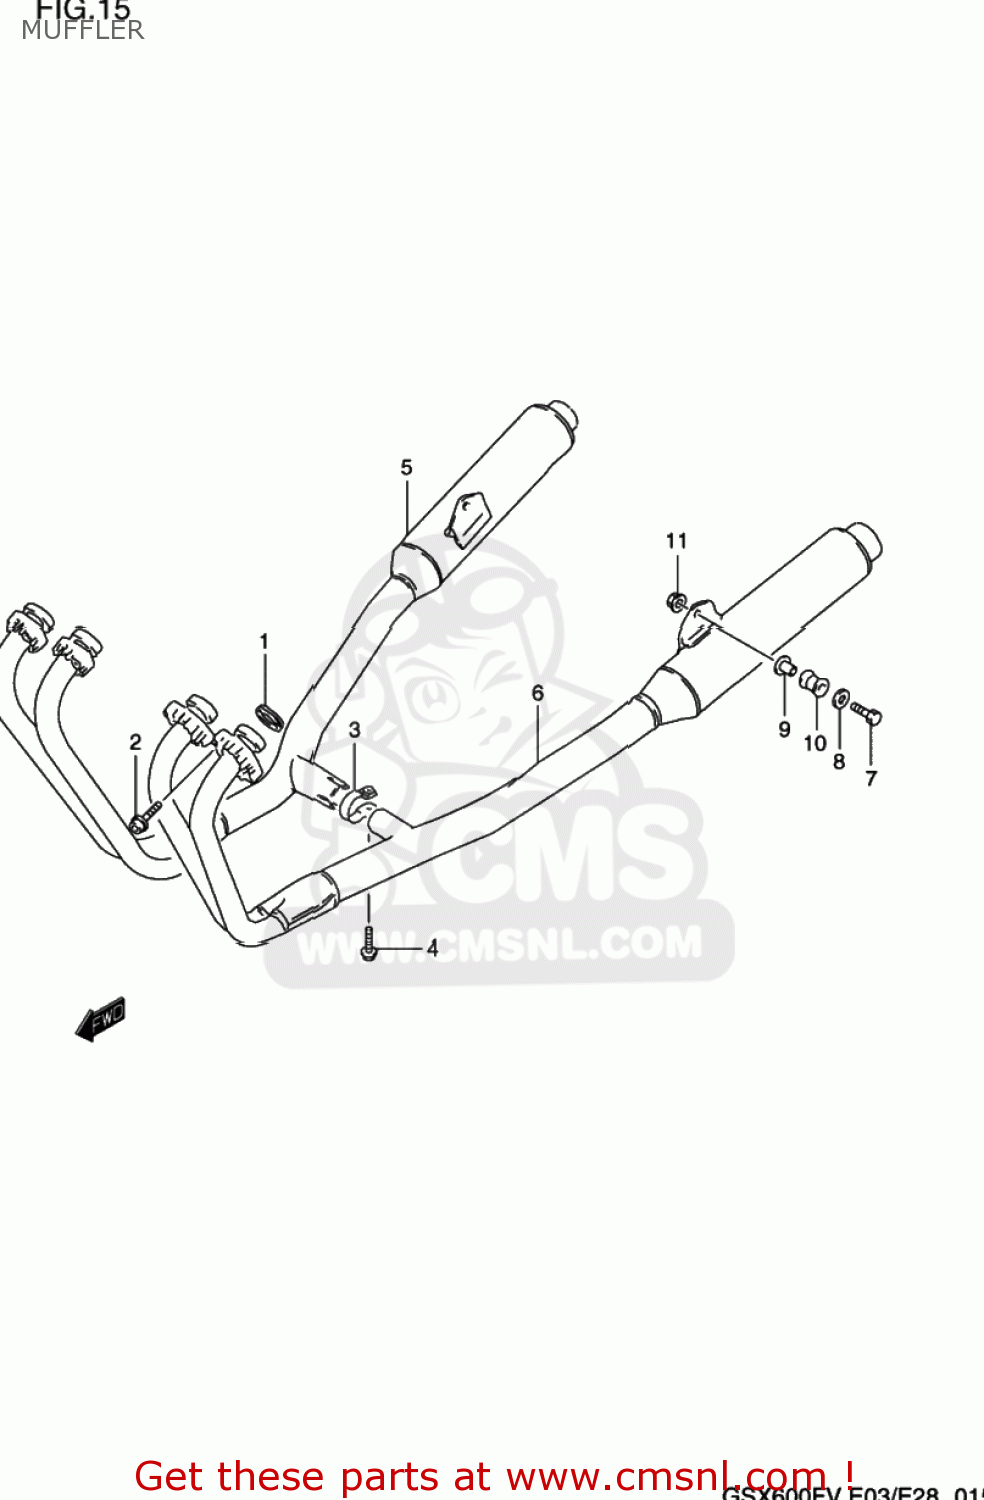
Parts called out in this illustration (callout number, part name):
1	GASKET,EXHAUST (NAS)
2	BOLT
3	CLAMP,MUFFLER CONNECTOR
4	BOLT
5	MUFFLER ASSEMBLY,RIGHT
6	MUFFLER ASSY,L
7	BOLT(8X40)
8	WASHER (8.1X33X1.6)
9	SPACER(8.6X12X24.2)
10	CUSHION
11	NUT
